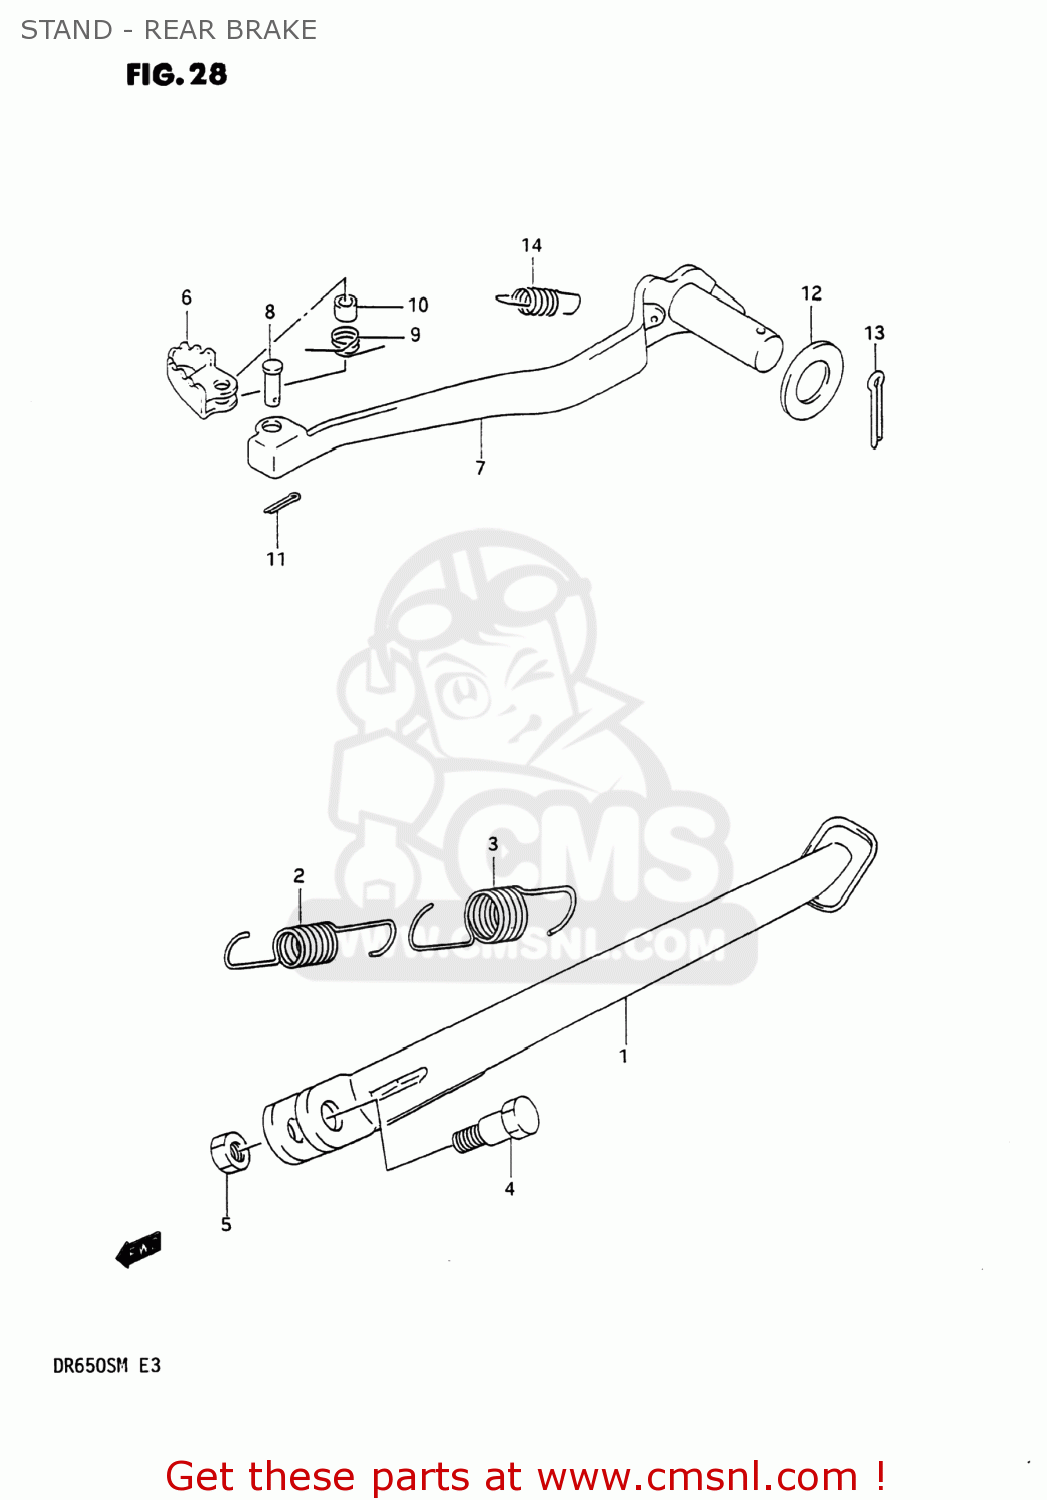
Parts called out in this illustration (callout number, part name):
1	STAND,SIDE
2	SPRING
3	SPRING
4	BOLT(10X30)
5	NUT
6	PEDAL,BRAKE
7	ARM,BRAKE PEDAL
8	PIN
9	SPRING
10	SPACER(9.2X9X6.5)
11	PIN
12	WASHER (17.6X34X2)
13	COTTER PIN
14	SPRING
